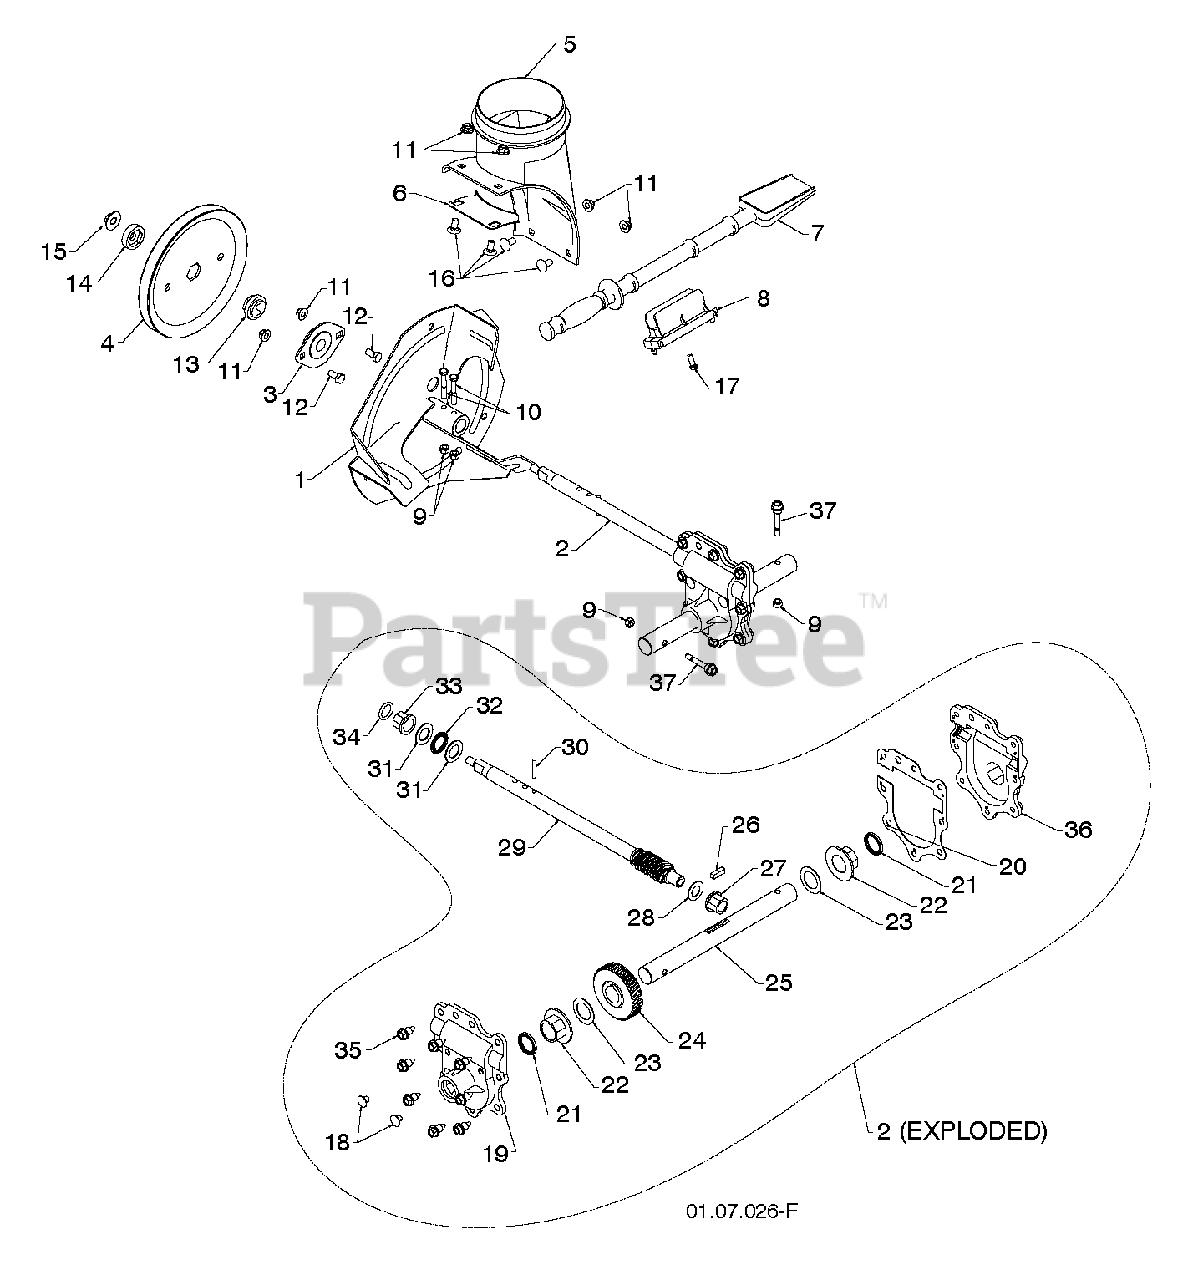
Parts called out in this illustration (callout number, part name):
1	IMPELLER ASSY
2	GEARBOX.ASM.AUGER.D-SHAFT
3	BEARING FLANGE
4	PULLEY.FLANGE.IMPELLER
5	BASE.DISCHARGE.CHUTE
6	BRACKET, CORNER DISCHARGE
7	CLEAN OUT TOOL
8	CLIP.CLEANOUT.TOOL
9	LOCKNUT
10	SCREW.HEX.HD1/4-20X
11	NUTNYLOK.FLRANGE.5/16-18
12	BOLT, HEX HEAD 5/16-18
13	HUB.IMP.PULLEY.D-SHAFT
14	SLEEVE.IMP.PULLEY.D-SHAFT
15	NUT
16	BOLT.CARRIAGE.5/16-18X
17	SCREW.HWH.13-16-5.8.BZP
18	CASE PLUG
19	GEAR.BOX.COVER.RIGHT.SIDE
20	GASKET.GEAR.BOX
21	OIL SEAL
22	FLANGE BUSHING-1"
23	WASHER TRUST 1"
24	WORM GEAR
25	AUGER SHAFT
26	KEY, SQUARE 1/4 X .875
27	FLANGE BUSHING-5/8
28	WASHER, THRUST 5/8
29	SHAFT.IMPELLER.D-SHAFT
30	PIN, ROLL 3/16 X 1-1/8
31	WASHER, THRUST 3/4
32	BEARING TRUST 3/4
33	BUSHING, FLANGE 3/4
35	HEX SCREW-5/16 X 3/4
36	GEAR.BOX.COVER.LEFT.SIDE
37	BOLT, SHOULDER SHEAR
